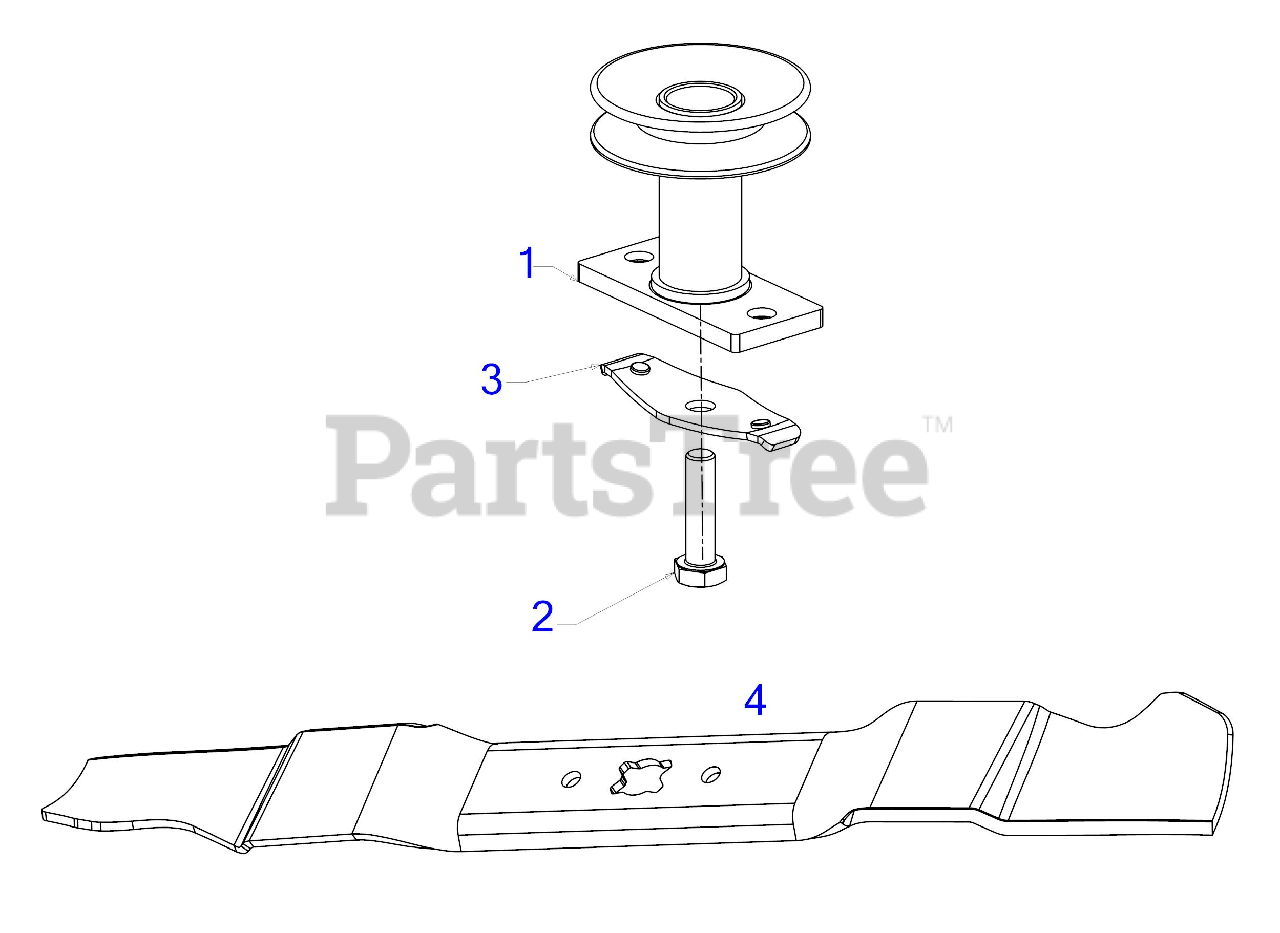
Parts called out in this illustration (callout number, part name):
1	ADAPTER ASSEMBLY (7/8 ID x .430 SP)
2	SCREW 3/8-24 x 1.50 GR8
3	BLADE BELL SUPPORT
4	21" BLADE (MULCH)
4	Cub Cadet 21" MULCH BLADE
4	Genuine Factory Parts 21" MULCH BLADE
4	Genuine Factory Parts 21" MULCHING BLADE (0741A)
4	21" BLADE (MULCH) (XTREME)
